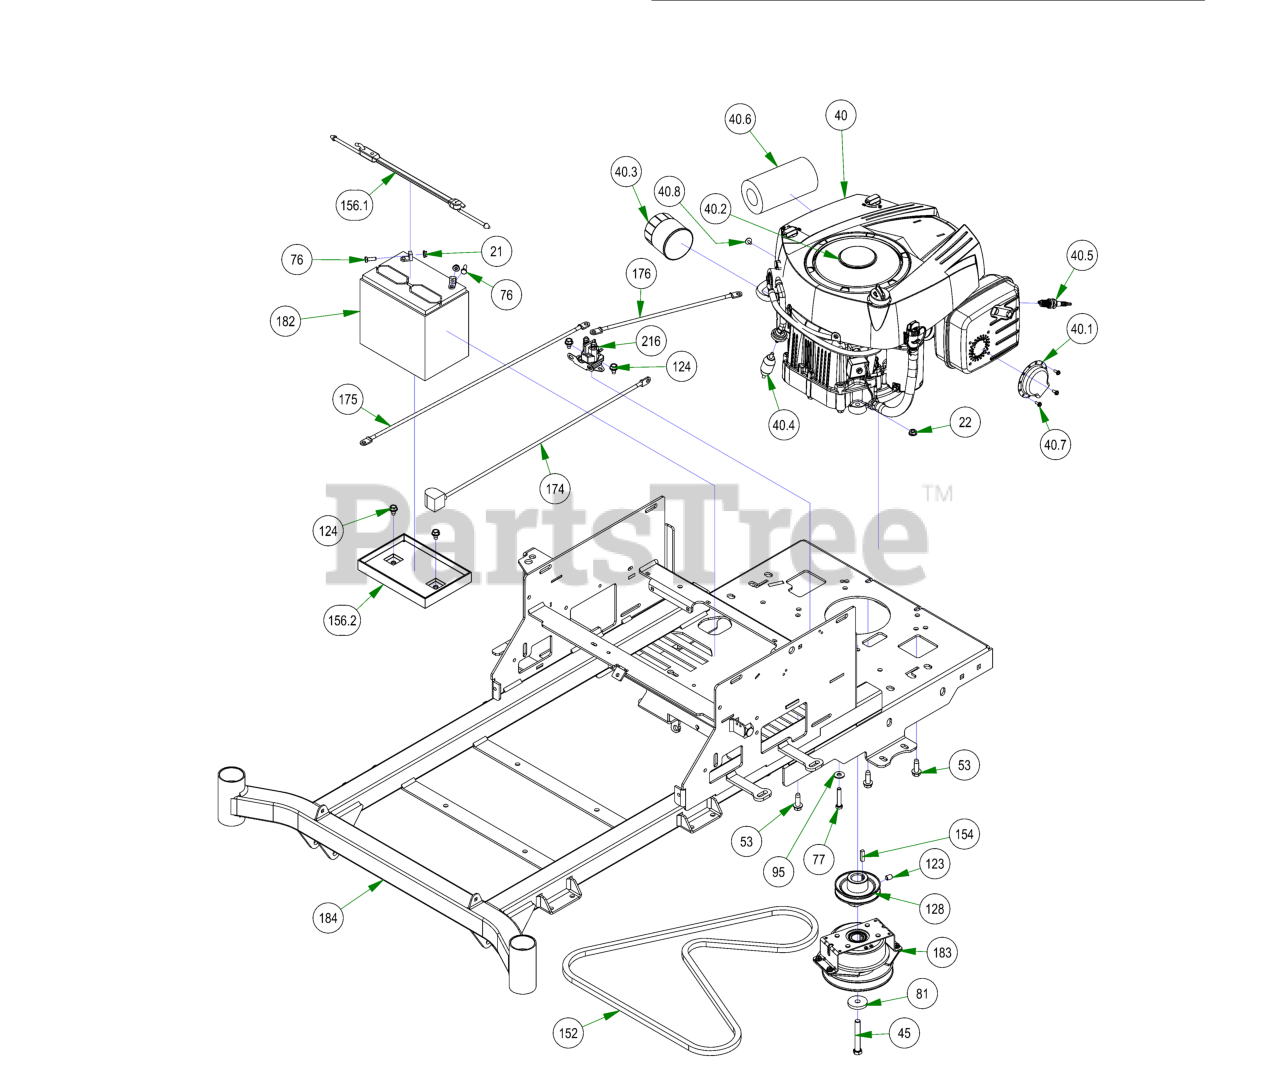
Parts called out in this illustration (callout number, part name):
21	1/4-20 HEX SERRATED FLANGE NUT HARD/ZINC
22	5/16-18 HEX SERRATED FLANGE NUT HARD/ZINC
40	19 HP Briggs Engine
40.1	Muffler Deflector- P/N-222573
40.2	Briggs 19HP Rotating Screen
40.3	Oil Filter
40.4	FUEL FILTER
40.5	Spark Plug
40.6	19/21 HP Briggs Air Filter
40.7	Muffler Deflector Screws -P/N-96046
40.8	Choke cable screw/washer- P/N-96073
45	7/16-20x3” Hex Bolt GR 8 W/ Patch
53	3/8-16 X 1-1/8HEX WASHER UNSLOT SERRATED (TRI-LOB) TRS
76	1/4-20 X 3/4 HEX CAP SCREW (GR.5) ZINC
77	5/16-18 X 1-3/4 HEX CAP SCREW (GR.5) ZINC
81	CLUTCH WASHER
95	5/16 USS FLAT WASHER (7/8 OD) ZINC
123	3/8-16 X 1/2 SOCKET SET SCREW (CUP PT) PLAIN
124	5/16-18 X 1/2 HWH unslot (F) tcs zinc
128	3-3/4" Motor Pulley
154	1/4 X 1 SQ MACHINERY KEY 1018 STL PLN
156	2023 Battery Hold Down Assembly Strap
156.1	2023 Rubber Battery Hold Down Strap
156.2	Battery Tray
174	24 inch Black Cable – MZ/ZT
175	24" Red Battery Cable
176	12 in red battery cable
182	SP-35 Battery
184	2023 MZ 42-48 Frame - Painted
